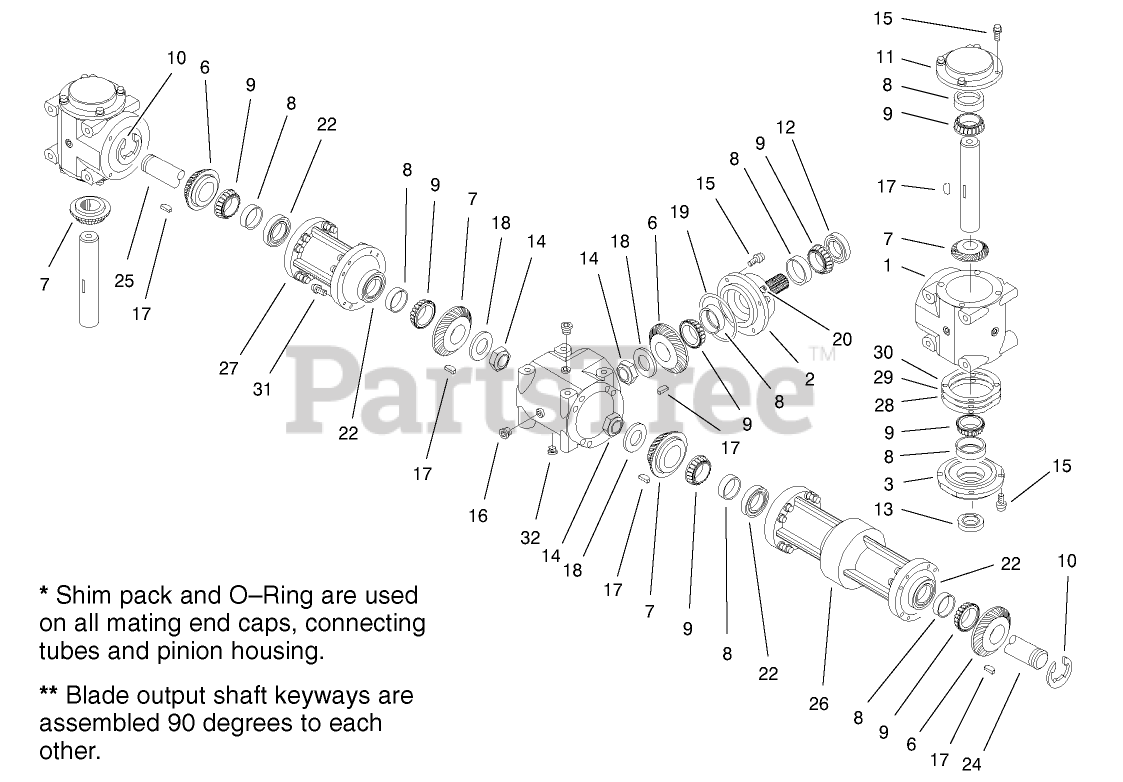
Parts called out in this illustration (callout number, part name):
2	HOUSING - PINION
3	CAP-END, OPEN
6	GEAR - 27 TOOTH
7	GEAR - 29 TOOTH
8	Bearing-Cup
9	Bearing-Cone
10	CLIP-RETAINING
11	CAP-END, CLOSED
13	SEAL
14	NUT-JAM
17	KEY-WOODRUFF
18	WASHER
19	O-RING
24	SHAFT - CONNECTING, LONG
25	SHAFT - CONNECTING, SHORT
26	FLANGE - CONNECTING, LONG
27	FLANGE - CONNECTING, SHORT
28	SHIM-BROWN, .010IN
29	SHIM-BLUE, .005IN
30	SHIM-GREEN, .003IN
32	PLUG-MAGNETIC
